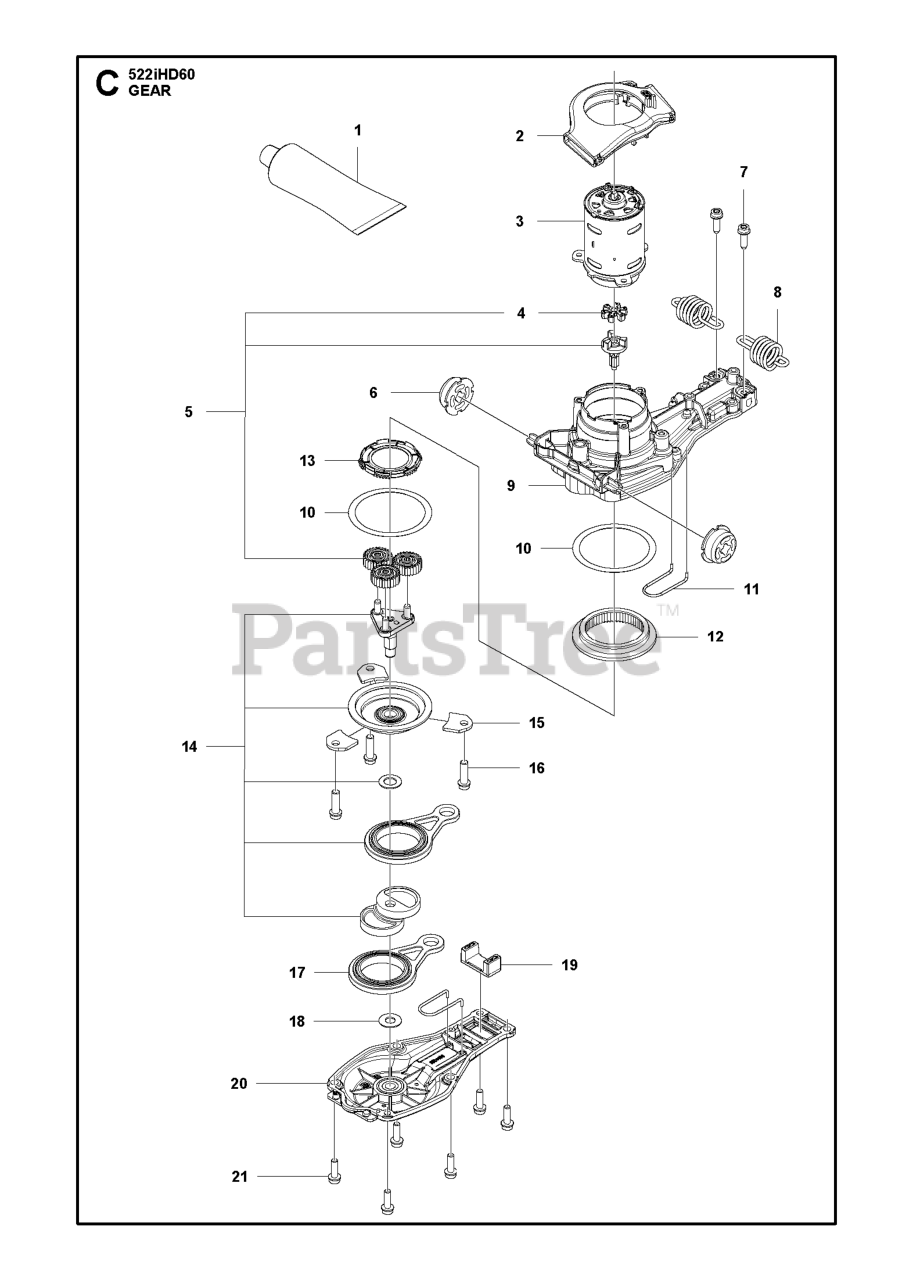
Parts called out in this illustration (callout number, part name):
1	GREASE 20G HEDGE TRIMMER GEAR
16	SCREW ITXSCM M6X20 T27 12.9 T
19	SEALING PLASTIC
